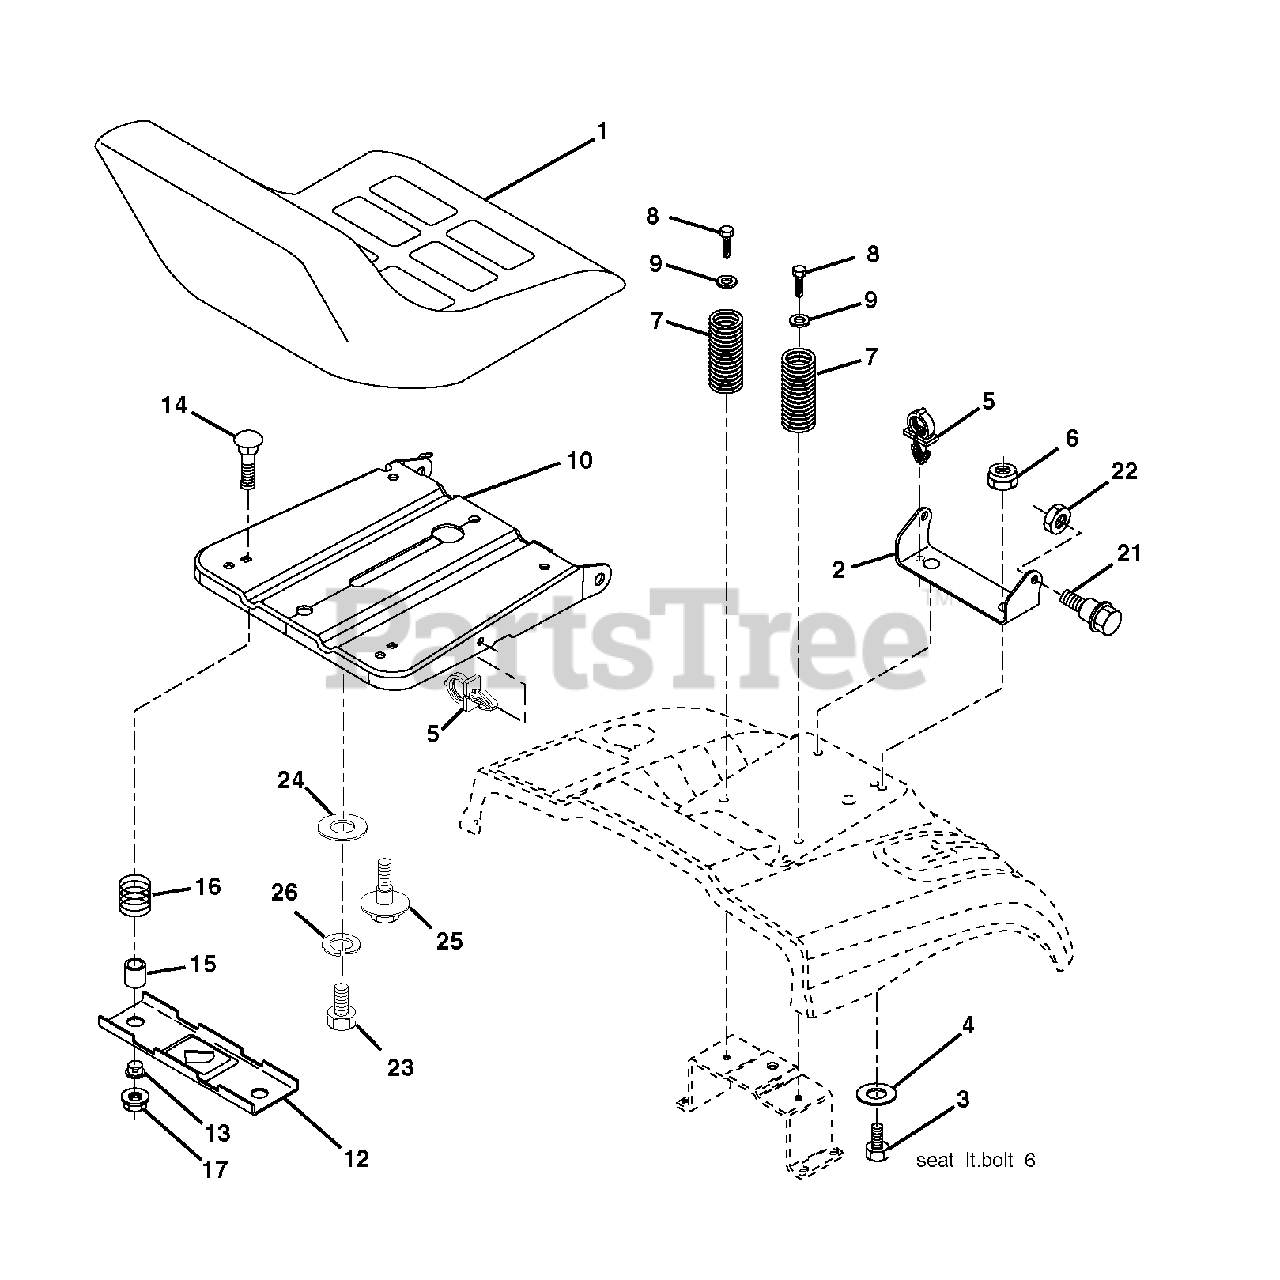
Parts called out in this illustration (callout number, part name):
1	SEAT.XG090.BLK.KB/BLT.NO-LOG
2	SEAT PIVOT BRKT
4	WASHER PM
5	PUSH CLIP
6	NUT
7	SPRING COMPRESSION
8	SCREW 3/8-16X1
9	WASHER
10	PAN.ASM.SEAT.1SLOT
12	BRKT.MNTNG.SWITCH.SEAT
14	BOLT.ROUND.HEAD.SQUARE.NECK
15	SPACER SPLIT 28X.96
17	NUT T
21	BOLT.SHOULDER.5/16-18
22	NUT.71038.31-18.HEX.NYLOCK
23	BOLT.HEX.BLACK
25	BOLT,SHOULD
26	LOCKWASHER
